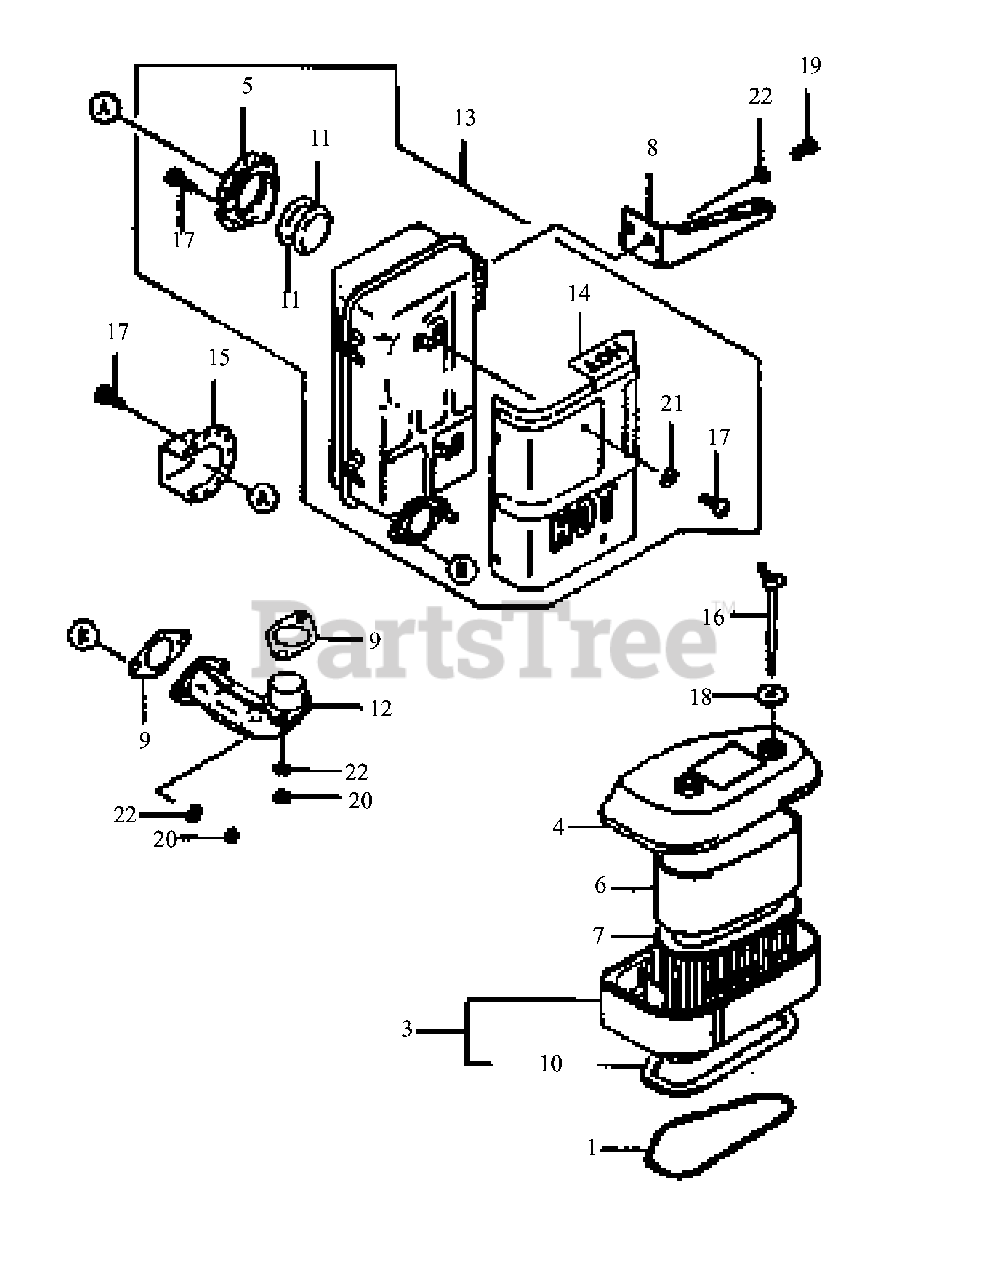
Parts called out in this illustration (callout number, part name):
1	Gasket, Air Filter
3	Case, Air Filter
4	Cap, Air Filter
6	Element, Pre Cleaner
7	Element, Air Filter
9	Gasket, Muffler
11	Arrester, Spark
14	Cover, Muffler
15	Cover, Muffler
18	Washer
